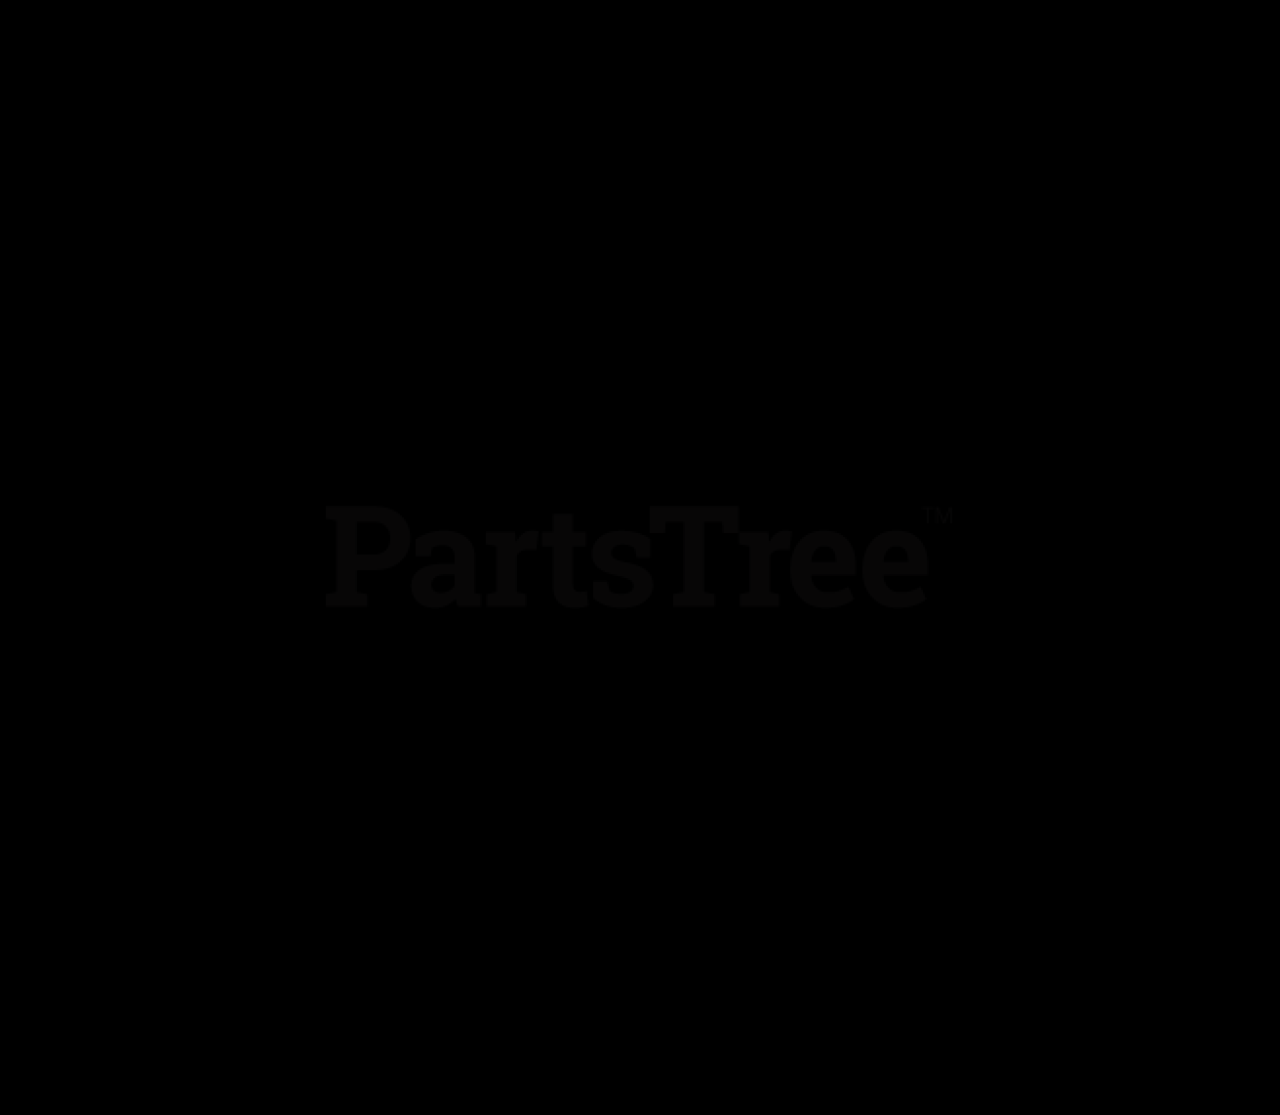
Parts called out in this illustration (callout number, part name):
1	Decal, Mower Pan Head Danger
2	Set, Decal – Common Danger/Fuel
3	Decal, Hot Surface
4	Decal, Warning
5	Decal, Instructional
6	Decal, Danger Fan
7	Decal, XDZ
8	Decal, Diesel (992215, 218)
9	Decal, Liquid Cooled
